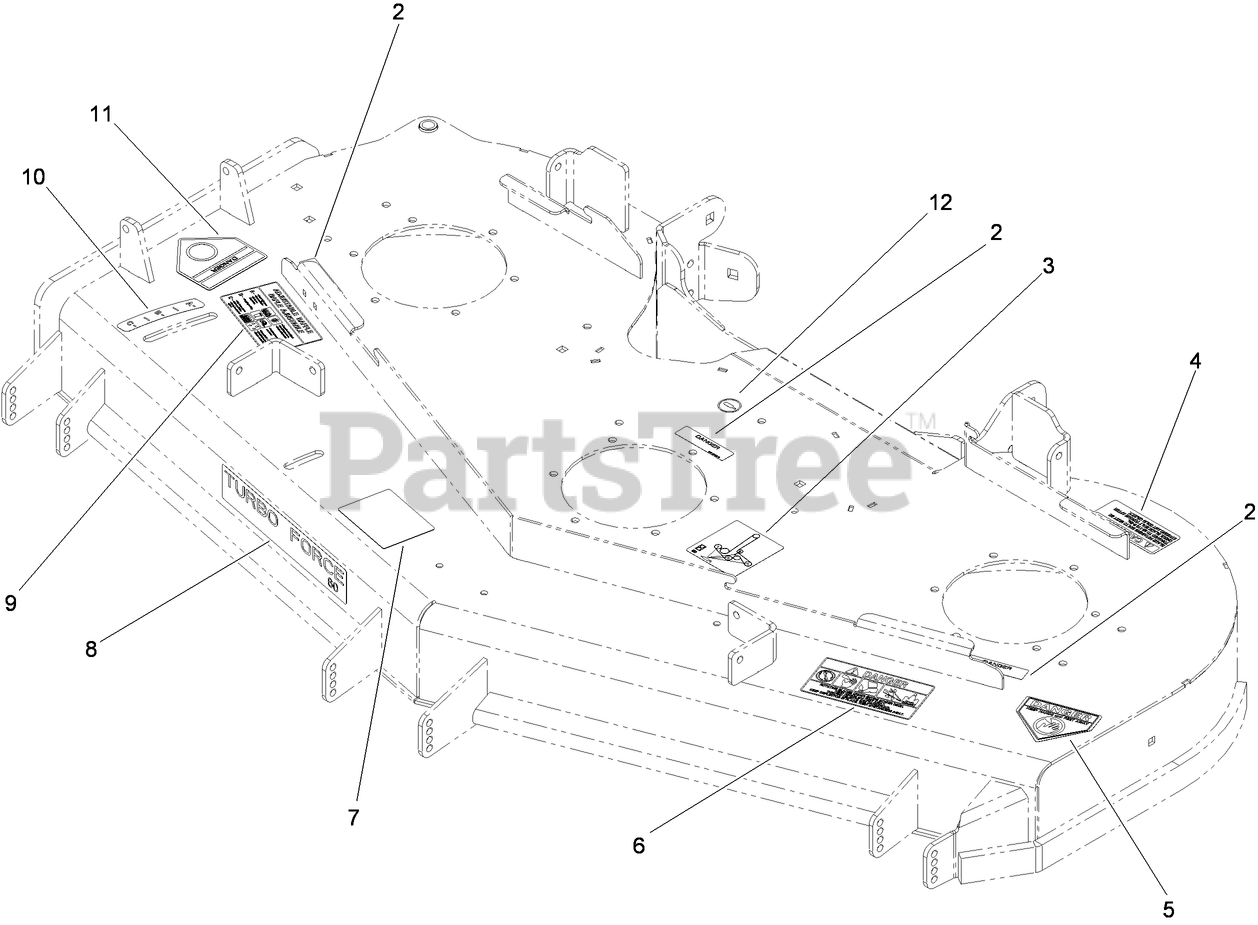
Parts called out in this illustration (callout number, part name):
2	DECAL-COVER, MISSING
3	DECAL-ROUTING, DECK BELT
4	DECAL-TORQUE
5	DECAL-DANGER
6	DECAL-DANGER, THROWN OBJECT
7	DECAL-SCALP, ANTI
9	DECAL-ADJUSTMENT, BAFFLE
10	DECAL-SETTING, BAFFLE
11	DECAL-DANGER
12	DECAL-GREASE
